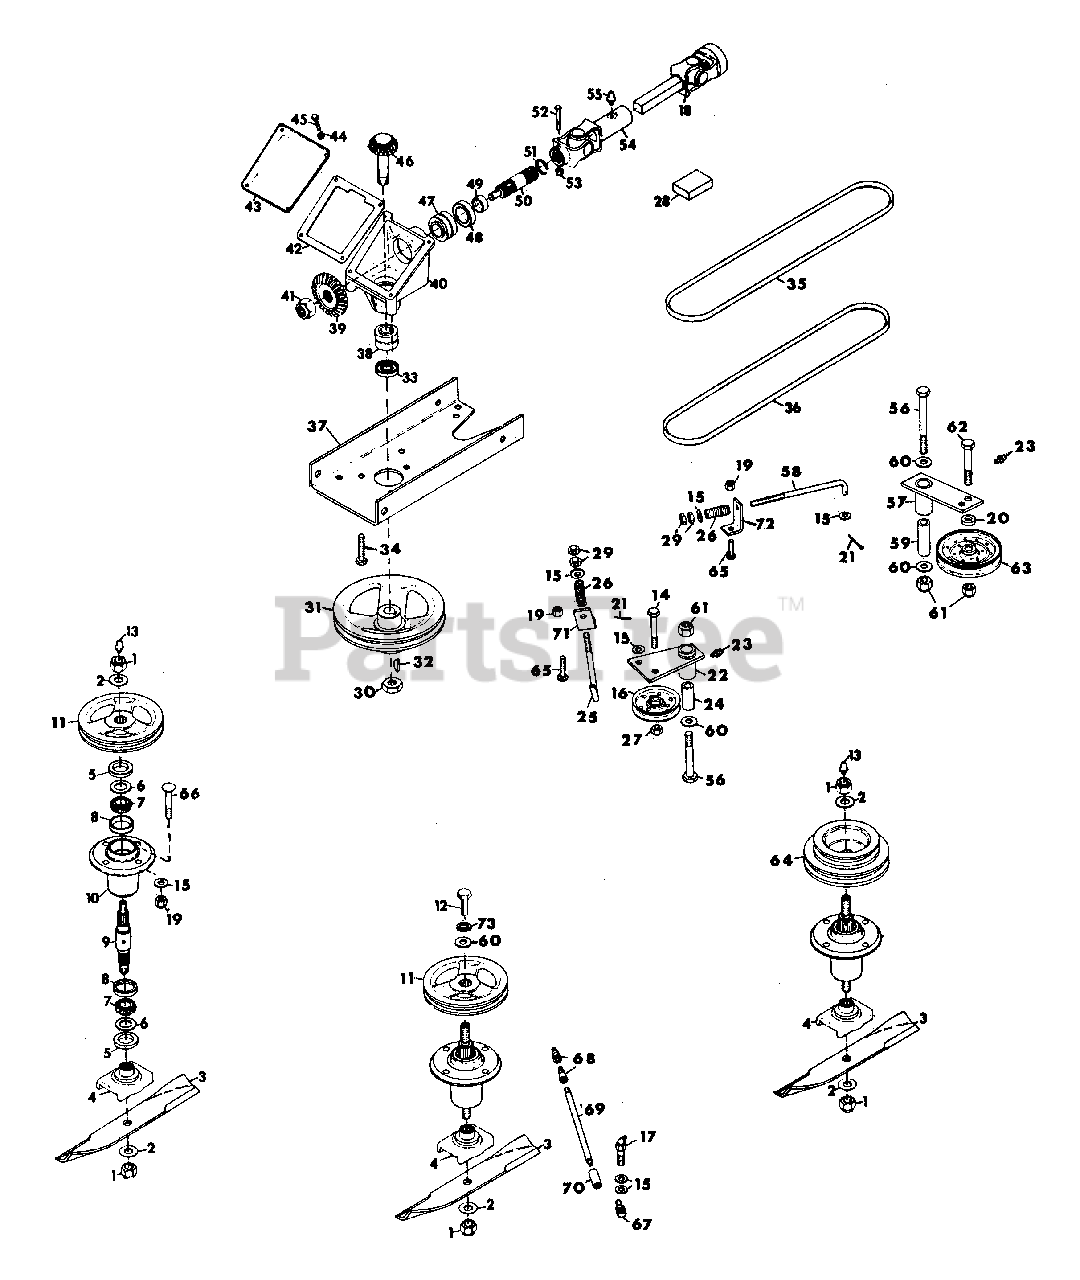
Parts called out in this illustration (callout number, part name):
1	Nut, Lock 5/8-11
2	Washer, Flat .656 x 1.312 x .095
4	Cradle, Blade
5	Seal, Steel
6	Washer, Flat; .975 x 1.970 x .030
7	Cone, Roller Bearing
8	Cup, Roller Bearing
9	Shaft, Left and Right Spindles
9	Shaft, Center Spindle
10	Housing, Left and Right Spindles
10	Housing, Center Spindle
11	Pulley
12	Bolt, Special
13	Fitting, Lube 1/8 NPT
14	Bolt, Hex 3/8-16 x 1.75
15	Washer, Flat .406 x .812 x .065
16	Sheave, Idler
17	Fitting, Lube 65 Deg. NPT
18	Universal Shaft, Male
19	Nut, Lock; 3/8-16
20	Spacer
21	Pin, Cotter .062 x 1.000
22	Weldment, Idler Pivot
23	Fitting, Lube; 1/4-28 NPT
24	Spacer
25	Rod, Idler
26	Spring
27	Nut, Lock 3/8-16
28	Kit, Repair Universal Shaft, Male
28	Kit, Repair Universal Shaft, Female
29	Nut, Hex; 3/8-24
30	Nut Jam 3/4-10 Hex Heavy
31	Pulley, Gearbox
32	Key, Woodruff 3/16 x 5/8 No. 61
33	Seal, Oil
34	Bolt, Hex; 1/2-13 x 1.000
35	Belt, A Section
36	Belt, B Section
37	Plate, Support
38	Bearing, Taper Roller .750
39	Gear, Bevel
40	Housing, Gear
41	Nut, Lock; 3/4-10
42	Gasket, Gear Housing
43	Cover, Gear Housing
44	Washer, Lock 1/4 Spring
45	Bolt, Hex 1/4-20 x .50
46	Pinion Gear
47	Bearing, Taper Roller 1.000
48	Seal, Oil
49	Spacer
50	Shaft
51	Ring, Retaining; 1.000 Shaft
52	Bolt Hex 1/4-20 x 2.250
53	Nut, Lock 1/4-20
54	Universal Shaft, Female
55	Fitting, Lube 1/4-28
56	Bolt Hex 1/2-13 x 3.500
57	Weldment, Idler Pivot
58	Rod, Idler
59	Spacer
60	Washer, Flat .500 x 1.250 x .083
61	Nut, Lock; 1/2-13
62	Bolt Hex 1/2-13 x 2.000
63	Pulley, Flat Idler
64	Double Pulley
65	Bolt 3/8-16 x 1.000 RD HD SQ NK
66	Bolt, 3/8-16 x 1.375 RD HD SQ NK
67	Elbow Adaptor 90 Deg. 1/8-27 NPT
68	Elbow, Street 1/8-27
69	Nipple, Pipe 1/8-27 x 5.50
70	Coupling, Pipe 1/8-27
71	Support, Spring
72	Support, Spring
73	Washer, Lock 1/2 Spring
